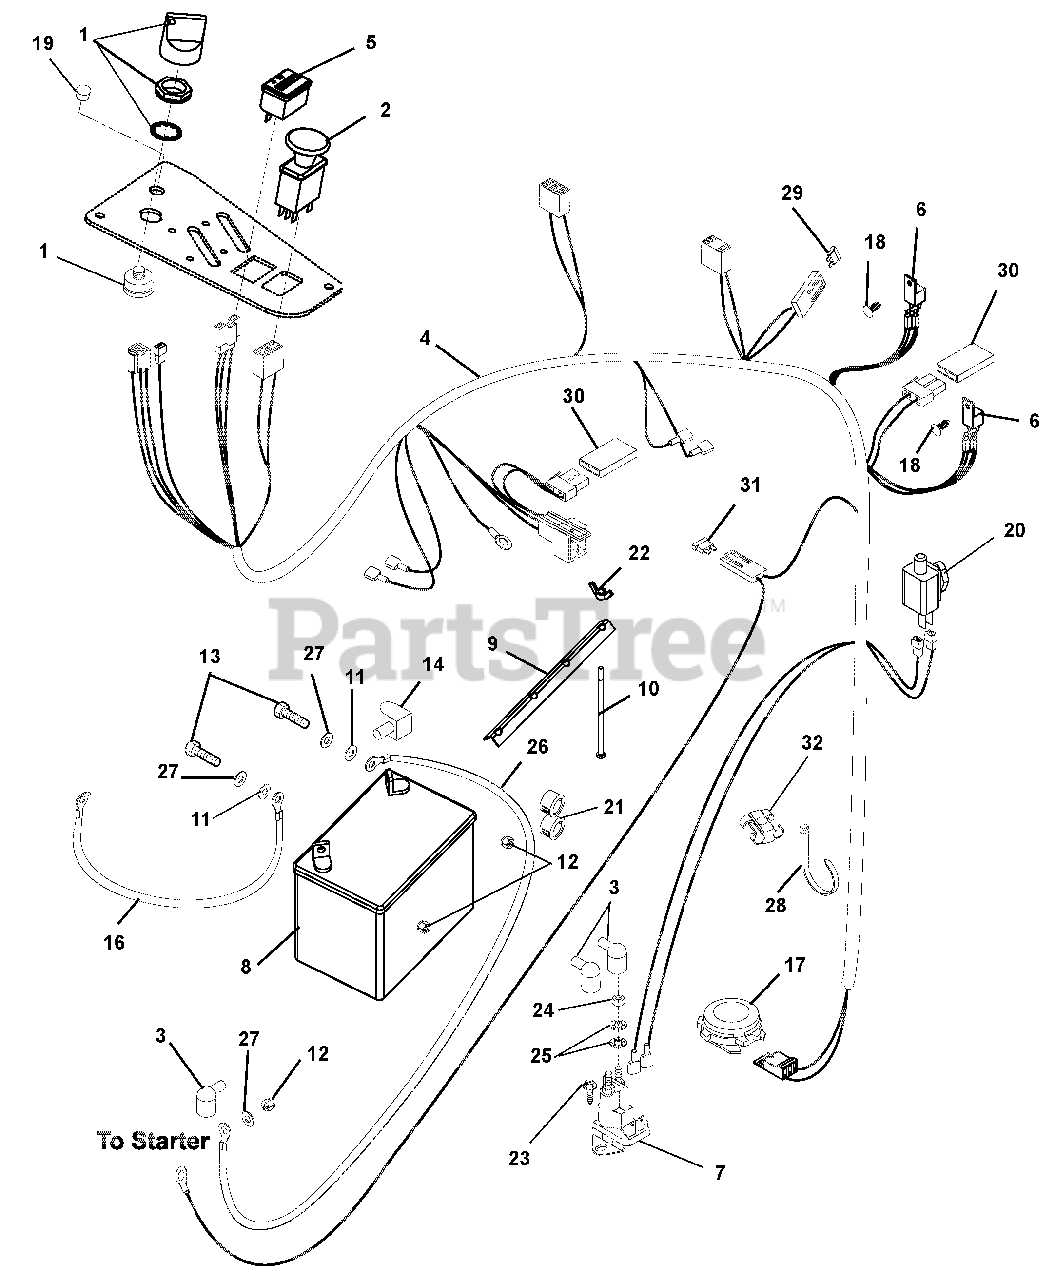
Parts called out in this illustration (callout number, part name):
1	Key, with Shield
2	Switch, Clutch
3	Boot, Eyelet Terminal
4	Harness- CZ Remote SOL.
5	Hour Meter – w/Maintenance
6	Relay, Sealed W/Diode
7	Solenoid
9	Hold Down
10	Bolt, Round Head Square Neck .25-20 x 7.50
11	Washer, Flat Steel .281 x .620 x .065
12	Nut, Hex .25-20
13	Bolt, Hex .25-20 x .75 Grade 5
14	Insulator
15	Cable, Positive Battery 9.00"
16	Cable, Negative Battery
17	Switch, Seat
18	Rivet, .25 Nylon Panel
19	Plug, Hole .50 Diameter
20	Switch, Single Pole (N.O.)
21	Bushing, Panel Snap .687 x .875 x .56
22	Nut, Locking Wing .25-20
23	Screw, Tapping .25-20 x .50 Hex Washer Head
24	Nut, Jam .31-24
25	Washer, Star Washer .31 x .078 Regular
26	Cable, Starter
27	Washer, Lock .25 x .062
28	Tie, Cable LG 5.50
29	Fuse 20AMP
30	Diode, Connector Shell
31	Fuse-25 AMP
32	Clip, T, .31-38
